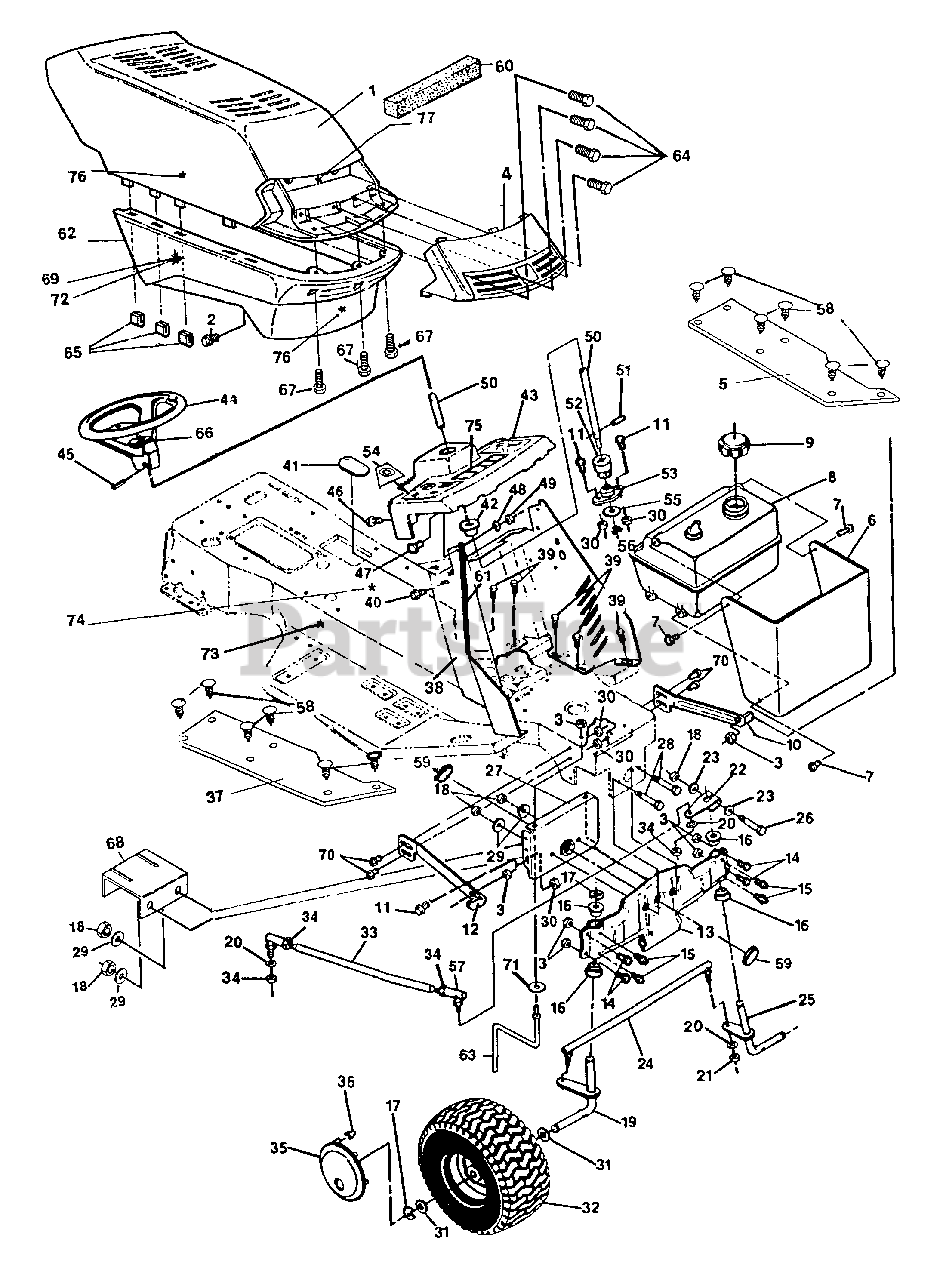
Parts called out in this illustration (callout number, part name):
2	Shoulder Bolt, 5/16-18 Thd.
3	Nut, Hx, Ctrlk, 5/16-18 Thd.
4	Lens, Headlight
5	Assembly, Foot Pad L.H.
6	Heat Shield
7	Screw, Hx Hd, Plastite 1/4 Dia. x 3/4 In.
8	Tank, Gas 1.5 Gal W/Sensor
8	Low Fuel Sensor
9	Cap, Fuel
10	Bracket, Hood L.H.
11	Screw, Hx Hd, 5/16 -18 x 3/4 In.
12	Bracket, Hood R.H.
13	Front Axle W/Bearings
14	Screw, Hx Hd, 5/16-18 x 5/8 In.
15	Grease Fitting
16	Bearing, Spindle
18	Nut, Hx, Ctrlk, 3/8-16 Thd.
19	Spindle, R. H.
20	Washer, Split, Lock 3/8 In.
21	Nut, Hx, 3/8-24 Thd.
22	Steering Arm, Upper
23	Washer, Flat, 25/64 In.
24	Assembly, Tie Rod
25	Spindle, L.H.
26	Screw, Hx Hd, 3/8-16 x 2-1/2 In.
27	Support Bracket, Front Axle
28	Screw, Hx Hd, 3/8-16 x 3 In.
29	Washer, Spring
30	Nut, Hx, Wd Fl Lk 5/16-18 Thd.
31	Washer, Flat, 3/4 In.
32	Wheel & Tire Assembly, Front
32	Tire, Rear
32	Wheel/With Bearing
32	Valve Stem
33	Drag Link
34	Nut, Hx, Jam, 3/8-24 Thd.
35	Hubcap, Front
36	Clip, Hubcap
37	Assembly, Foot Pad R.H.
38	Dash, Lower
39	Screw, Tap, 5/16-18 x 3/8 In.
40	Screw, Self-Tap, 1/4-20 x 1/2 In.
42	Bushing, Upper Steering
43	Dash, Upper
44	Steering Wheel
45	Pin, Spring, 1/4 x 2 In.
46	Screw, Tap, 1/4-20 x 1/2 In.
47	Screw, Hx Hd, 1/4-20 x 5/8 In.
48	Washer, Flat, 9/32 In.
49	Nut, Hx, Ctrlk, 1/4-20 Thd.
50	Shaft, Steering
51	Pin, Dowel
52	Pinion, Steering
53	Bearing, Flange
54	Plate, Electric Clutch
55	Washer, Flat, 1/2 In.
57	Ball, Joint, 3/8 Thd.
58	Ratchet Fastener
59	Plug, Front Axle
60	Foam, Hood Baffle
61	Wide Trim 18"
63	Belt Guide
64	Screw, #4-24 x 1/2 In.
65	Clip, Tinnerman
66	Decal, Gunsight Cent. Steer Wheel
67	Screw, #10 x 1/2 In.
68	Bracket, Stop
69	Decal, Pin Stripe R.H
70	Screw, Hex Fl, 5/16-18 x 3/4 In.
71	Washer, Internal Tooth
72	Decal, Pin Stripe L.H.
73	Decal, Wheel 4 Steer Husq.
74	Decal Oper Instr ERO Top Frame
75	Decal, Dash, Chg, Oil, Fuel, All Systems
76	Decal, Fender Rear, Hood, Husq.
77	Decal, Reflector
